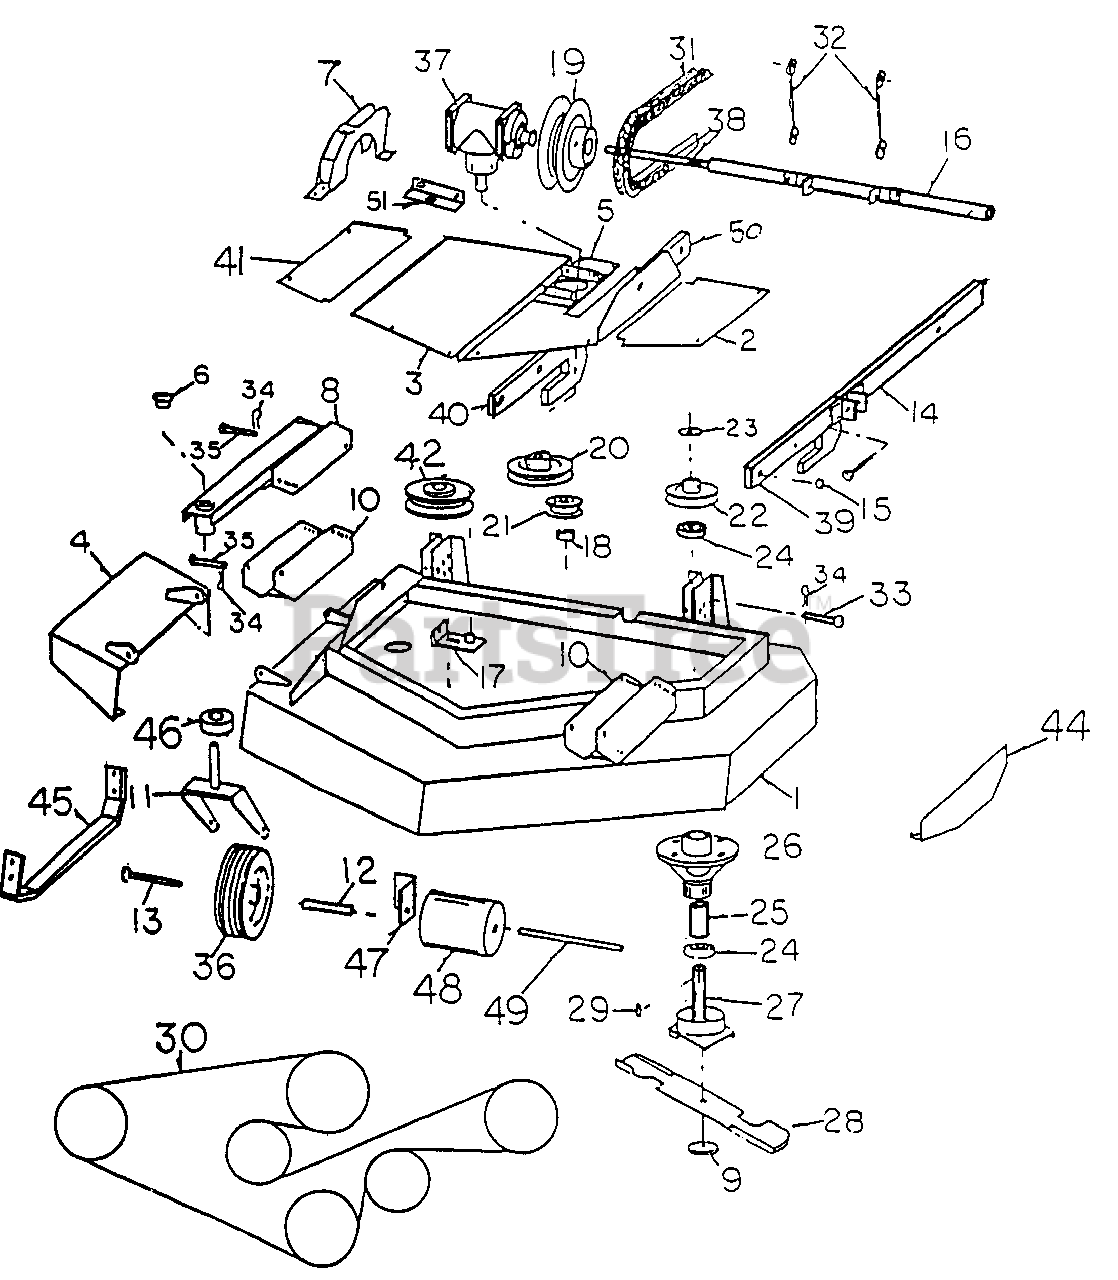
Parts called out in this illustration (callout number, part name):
1	MOWER DECK
5	GAUGE WHEEL BEARINGS
6	GAUCE WHEEL BEARINGS
8	GAGE WHEEL MOUNT
10	BRACKET, GAGE WHEEL MOUNT
11	FORK GAGE WHEEL
12	AXLE
13	AXLE BOLT
14	L.H. DECK LIFT ARM BACK ADJUSTABLE
15	BUSHING, DECK DECK LIFT ARM
17	BELT TIGHTENER
18	SPACER IDLER
19	PULLEY GEAR BOX
20	PULLEY GEAR BOX
21	5 IDLER
22	PULLEY SPINDLE
23	WASHER SPINDLE
24	BEARING SPINDLE
25	SPACER SPINDLE
26	HOUSING SPIN2LE
27	SHAFT SPINDLE
29	KEY SPINDLE
35	PINS, GACE WHEEL
38	CROSS BAR PI
39	L.H. DECK LIFT ARM ERONT ADJUSTABLE
40	R.H. DECK LIFT ARM ERONT ADJUSTABLE
41	COVER, RICHT HAND SIDE
42	PULLEY, IDLER LARGE
44	SHOE LEFT HAND SIDE
45	SHOE RIGHT HAND SIDE
47	ROLLAR BRACKET
50	R.H. DECK LIFT ARM BACK ADJUSTABLE
51	GEAR BOX MOUNT ANGLE
